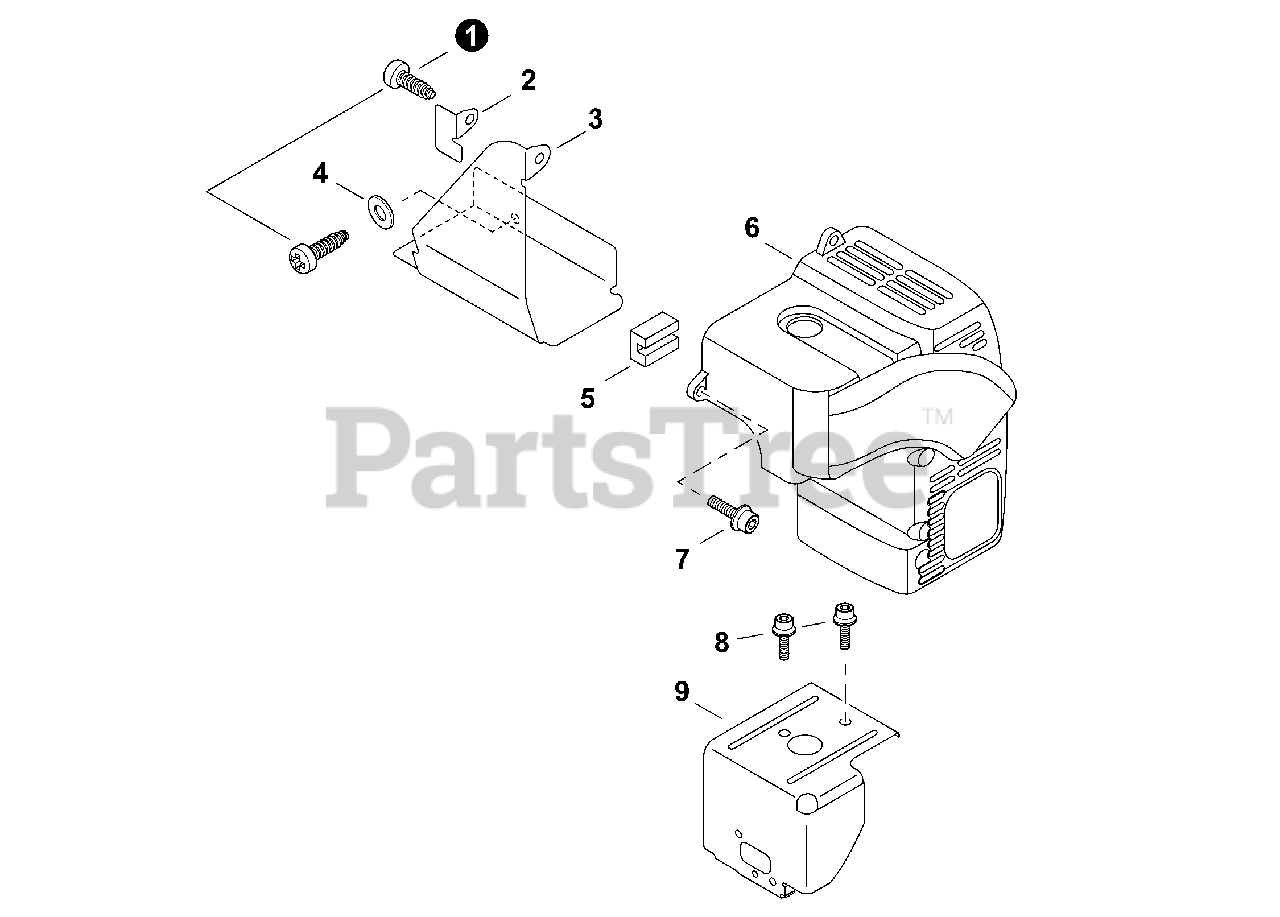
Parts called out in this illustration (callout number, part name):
1	SCREW 5×10
2	PLATE, ANGLE
3	INSULATOR, MUFFLER
4	WASHER 5.5×12×0.8
5	CUSHION
6	COVER, ENGINE
7	SCREW TAPPING 5×20
8	BOLT 5×8
9	COVER, CYLINDER
